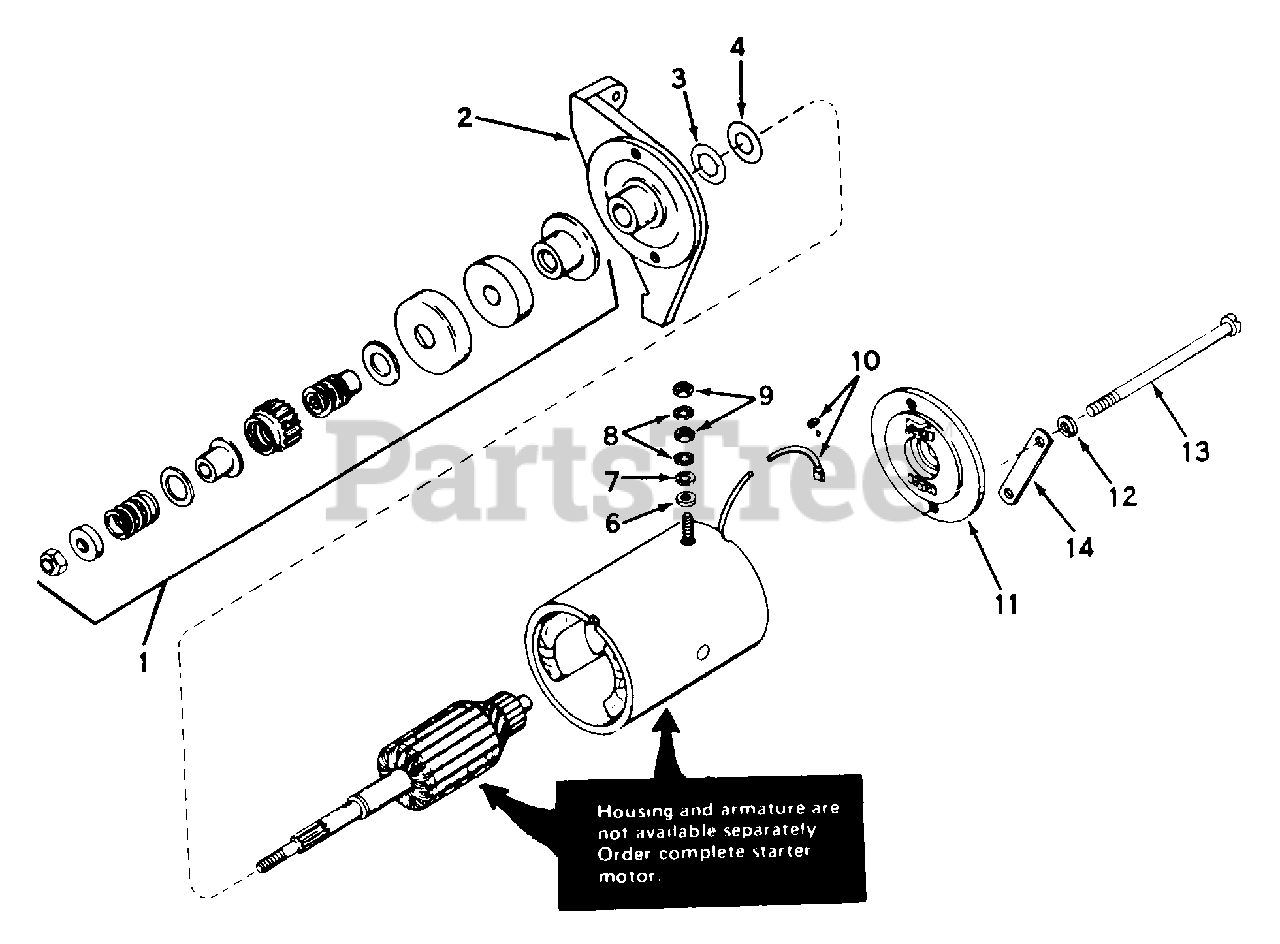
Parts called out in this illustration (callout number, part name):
1	"Drive Assy., Complete
2	Cap Assy., Drive end (9/16" bore)
3	Washer, Spacing
4	Washer, Spacing (.010" Thick)
6	Washer, Insulating
7	Washer, Plain
8	Washer, Lock
9	Nut, Hex, 1/4-20
10	Brush & Spring Kit
11	Cap Assy., Commutator end
12	Washer, Lock, 1/4
13	Bolt, Thru
14	Bracket, Support
